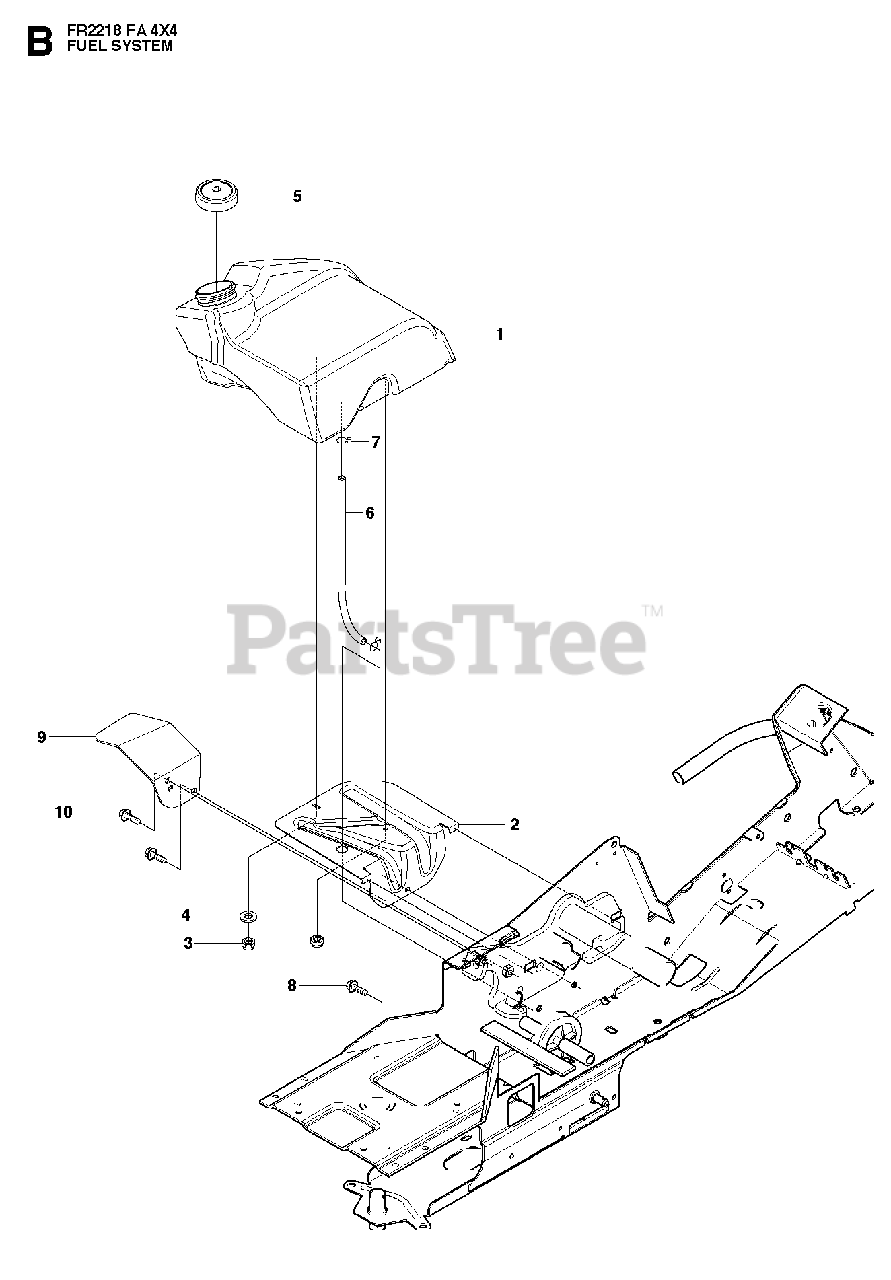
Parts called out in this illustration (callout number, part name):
3	LOCKNUT M6
4	WASHER
10	SCREW M10X25
